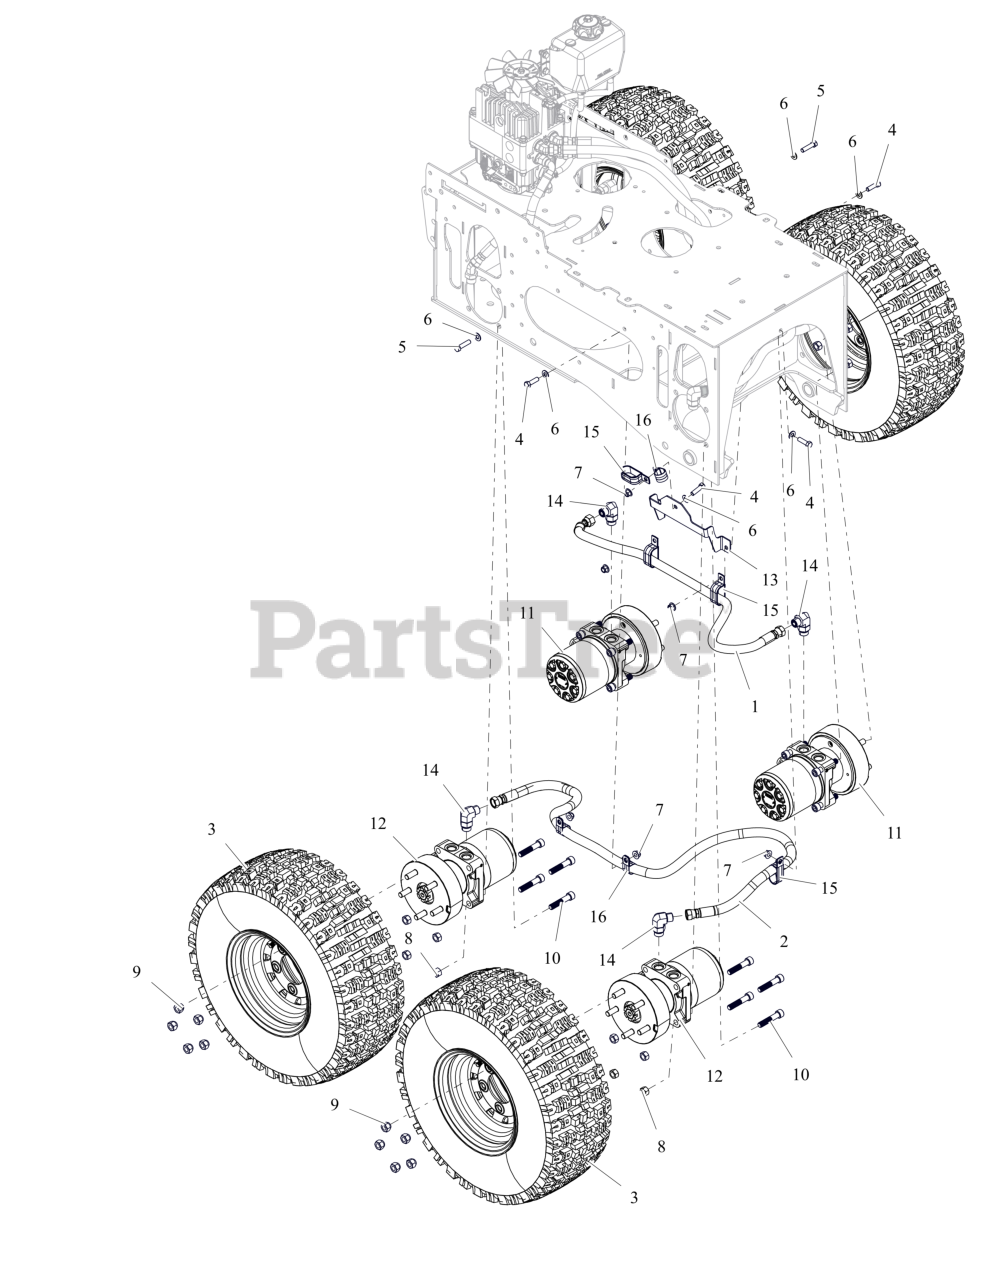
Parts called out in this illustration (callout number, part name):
1	ASM- HOSE LF MTR B/LR MTR A
2	ASM- HOSE RR MTR B/RF MTR A
3	ASSM TIRE\WHEEL 22X9-10 K502
4	BLT, HEX .38-16X1.25 G5 ZCC
5	BLT, HEX .38-16X1.50 G5 ZCC
6	WSHR,FLT .406X.812X.065 ZCC
7	NUT,NYL-FLG .38-16 GF ZCC
8	NUT,LK-CTR .50-13 GA ZCC
9	NUT, WHEEL .50-20 ZCC
10	SCREW- SOCKET HEAD CAP
11	MOTOR- WHEEL W/BRAKE - LH
12	MOTOR- WHEEL W/BRAKE - RH
13	BRKT- HOSE TRACTION
14	FITTING- HYD ELB 90-10-8 C5OLO
15	CLAMP- P-STYLE DUAL / 1.00 ID
16	CLIP- P-STYLE / 1.00 ID
